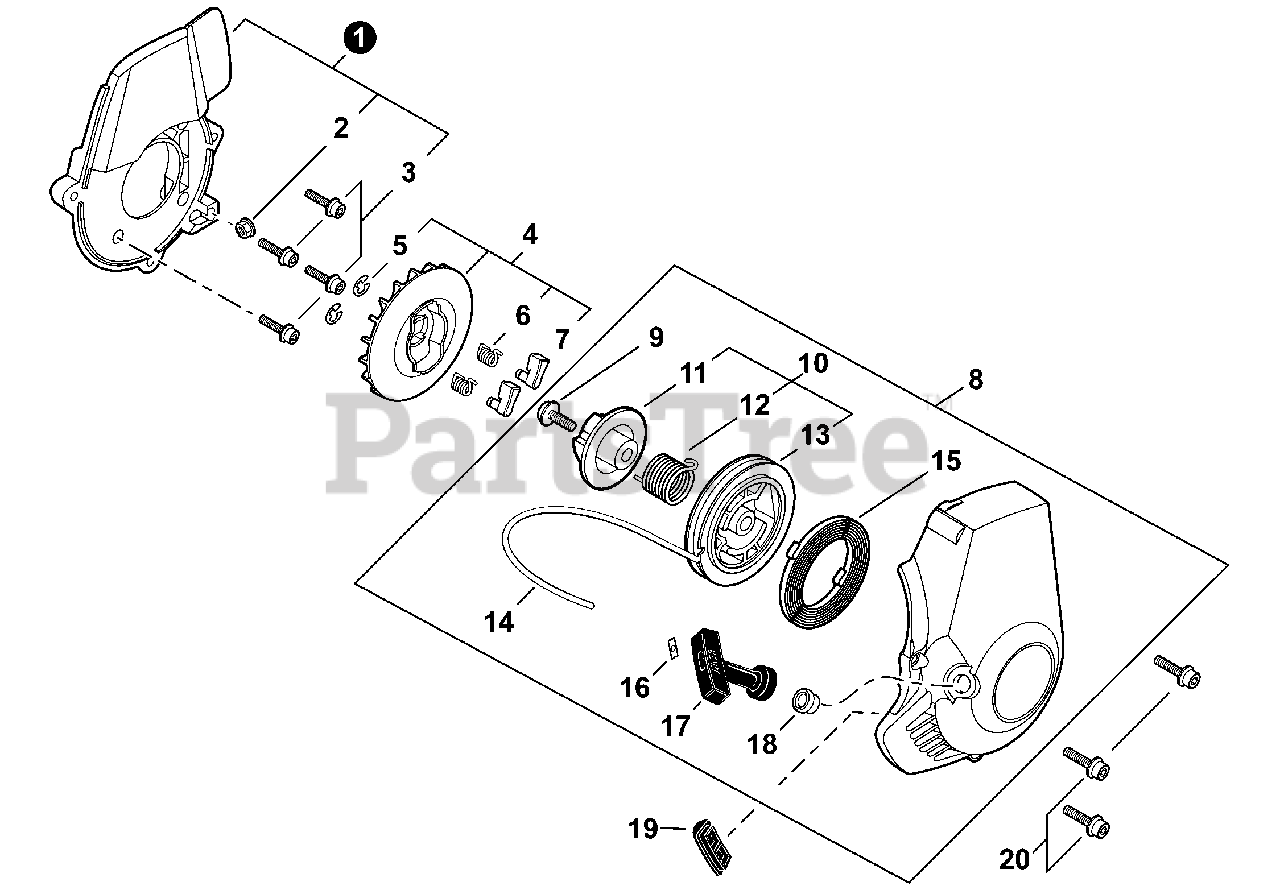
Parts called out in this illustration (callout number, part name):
1	SPACER ASSY.
2	NUT, FLANGE 5
3	BOLT 4×16
4	PAWL ASSY, STARTER
5	E-RING 4
6	SPRING, RETURN
7	PAWL, STARTER
8	STARTER, RECOIL
9	SCREW 5
10	REEL/CAM PLATE SET
11	PLATE, CAM
12	SPRING, TORSION
13	REEL, ROPE
14	ROPE, STARTER 3×700
15	SPRING, RECOIL
16	RETAINER, ROPE
17	GRIP, STARTER
18	GUIDE, ROPE
19	CUSHION
20	BOLT 5×14
